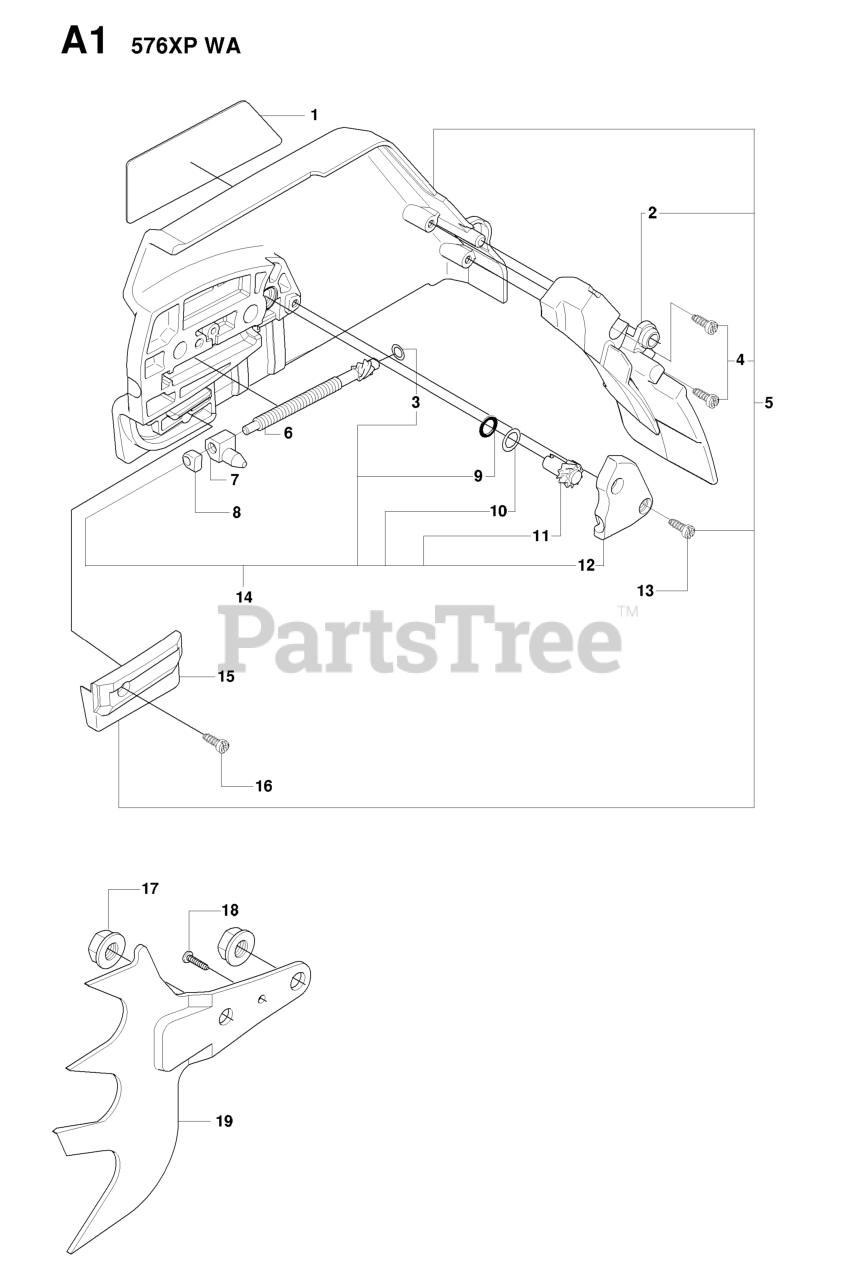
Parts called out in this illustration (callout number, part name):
5	CLUTCH COVER ASSY
6	ADJUSTER
11	RP ADJUSTER
14	KIT-CHAIN TENSIONER
15	CHAIN GUIDE
17	NUT M8 FLANGE
19	FELLING DOG
